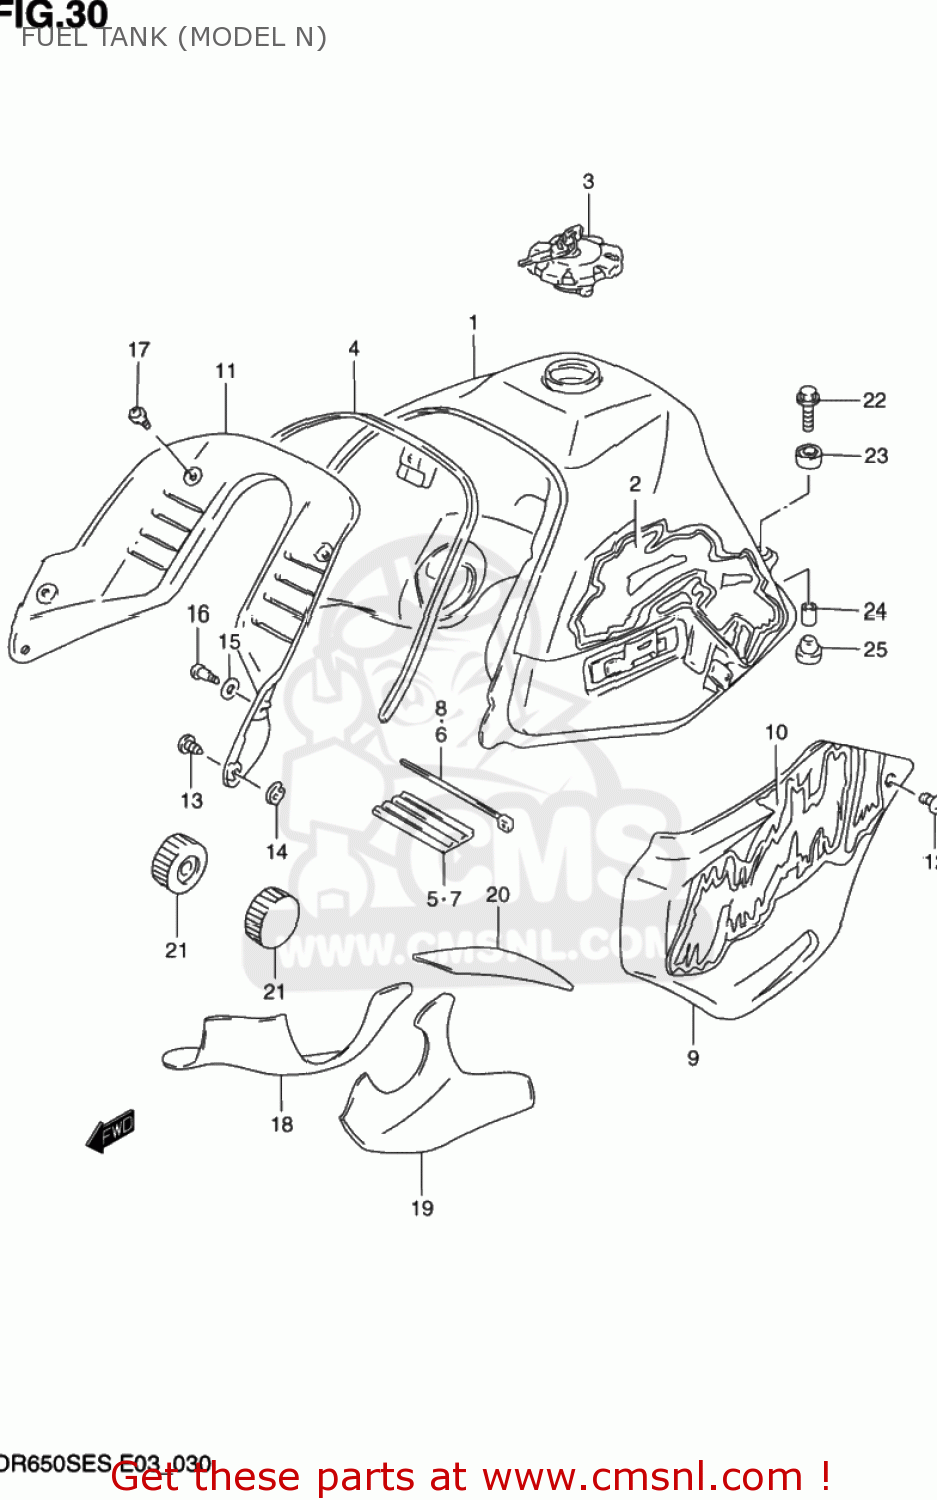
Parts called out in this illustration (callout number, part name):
1	TANK ASSEMBLY,FUEL
2	TAPE SET,FUEL TANK
3	CAP SET,FUEL TANK
4	MOLDING,FUEL TANK
5	CUSHION,FUEL TANK UPR FR
6	CLAMP
7	CUSHION,TANK UPR RR
8	CLAMP(L:300)
9	COVER,FUEL TANK,R
10	TAPE,TANK COVER,LEFT
11	COVER,FUEL TANK,FRONT
12	SCREW
13	VIS
14	NUT
15	WASHER (5.1X20X1.4)
16	SCREW(5X18)
17	SCREW, FRONT UPPER
18	SHIELD,FUEL TANK,RIGHT
19	SHIELD,FUEL TANK,LEFT
20	SHIELD,FUEL TANK,CENTER
21	CUSHION,FUEL TANK FR
22	BOLT
23	CUSHION
24	SPACER
25	CUSHION
